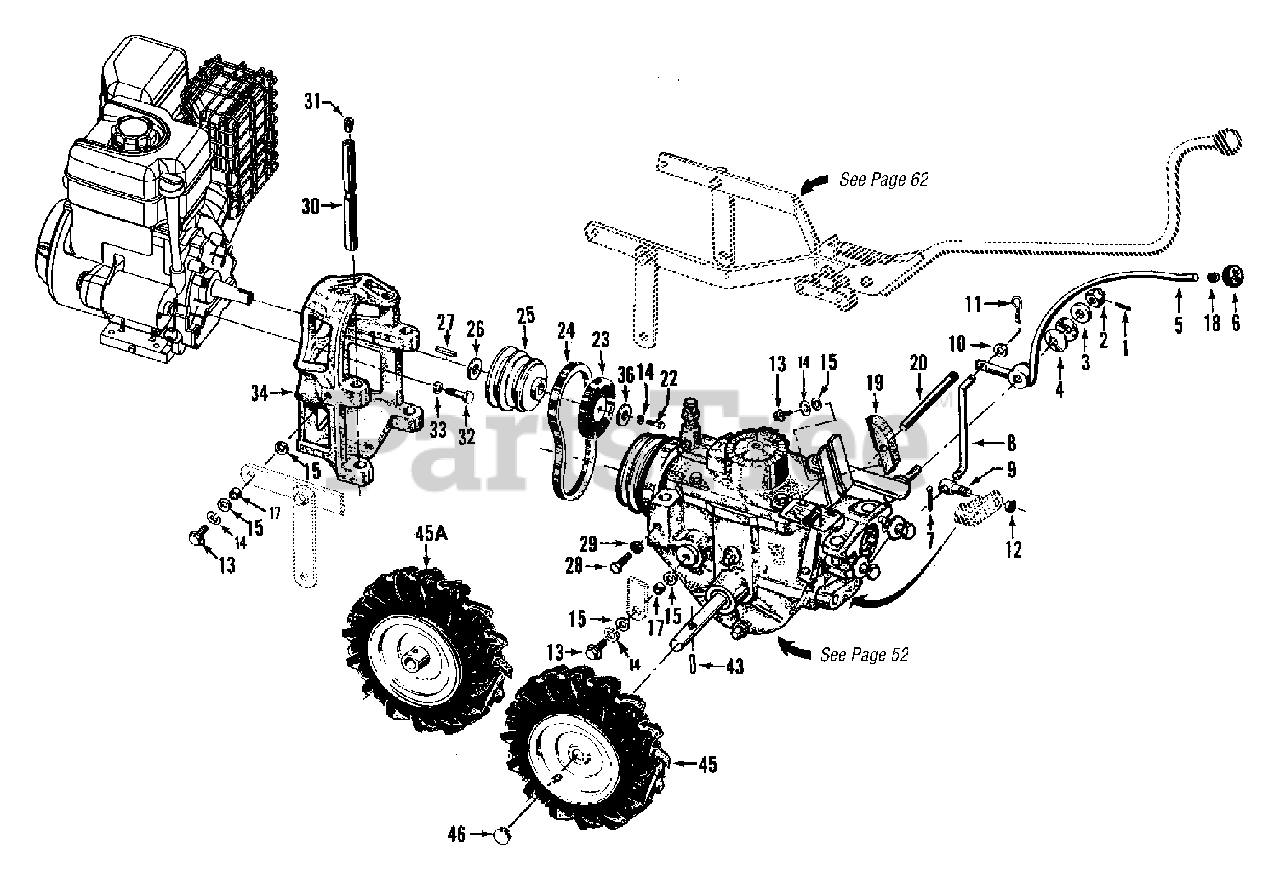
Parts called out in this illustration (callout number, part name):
1	Pin-spring, 1/8"
2	Nut-castle (slotted), 1/2"-20
3	Washer-shoulder, 1/2"
4	Washer-disc spring
5	Lever-wheel speed shift
6	Knob-wheel speed shift lever
7	Pin-cotter, 3/32" x 1"
8	Connecting rod, wheel speed -shift lever
9	Swivel-connecting rod
10	Washer-flat, 5/16", S.A.E.
11	Pin-hair cotter
12	Locknut-hex hd., 5/16"-18
13	Bolt-flanged hex hd., 3/8-16 x 1"
14	Lockwasher-spring lock, 3/8"
15	Washer-flat, 3/8", S.A.E.
17	Bushing-spacer, 19/64" (.300"lg.)
18	Ring-retaining (tolerance ring)
19	Block- belt adjustment, 3-7/8"
20	Rod- belt adjust., 7" with measuring gauge
21	Decal- engine stabilization
22	Bolt-hex hd., 3/8-24 x 1-1/2"
23	Disc-reverse
24	Belt-forward drive
25	Pulley-engine power take off
26	Shim-engine pulley, 1/16" As Req'd
26	Shim-as above, 1/32"
27	Key-engine pulley, 3/16"sq. x 2-1/2"
28	Bolt-hex hd., 5/16-18 x 1", Grade 5
29	Nut, hex, 5/16-18
30	Bar-engine mounting
31	Plug-thread protector, red plastic
32	Bolt-hex hd., 5/16-24 x 1-1/8"
33	Lockwasher-spring lock, 5/16"
34	Mount- engine to tiller
36	Washer, flat, .406 x 1.0 x .105
43	Pin- roll, 5/16" x 1-1/2"
45	Wheel & Tire Assy -
45A	Wheel & Tire Assy -
46	Cap-wheel hub
